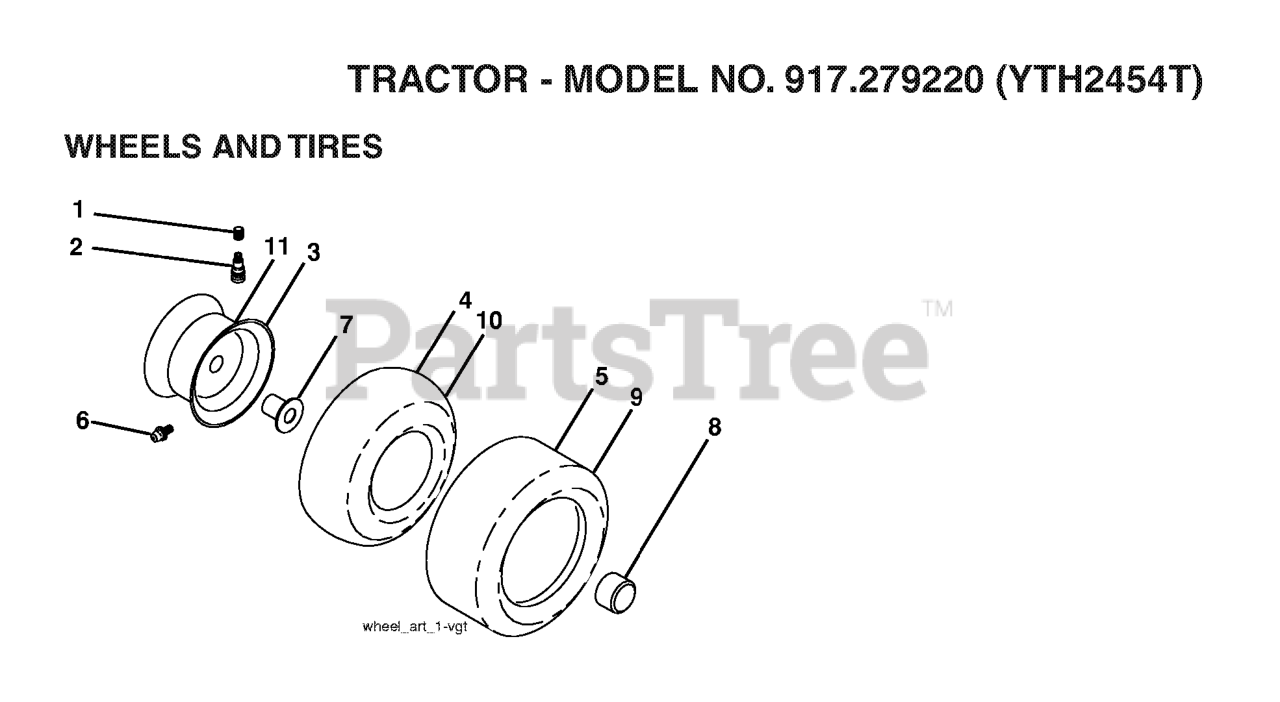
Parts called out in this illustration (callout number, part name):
2	VALVE STEM LT
3	RIM ASM 6" FRONT SILVER
4	TUBE.16X6.5/7.5-8
5	TIRE HEAVY DUTY
6	FITTING LT.
7	BEARING.FLANGE
8	CAP, AXLE BLK
9	TIRE.TS.20X10-8
10	TUBE.23X9.5-12
11	RIM ASM 8" REAR SILVER
